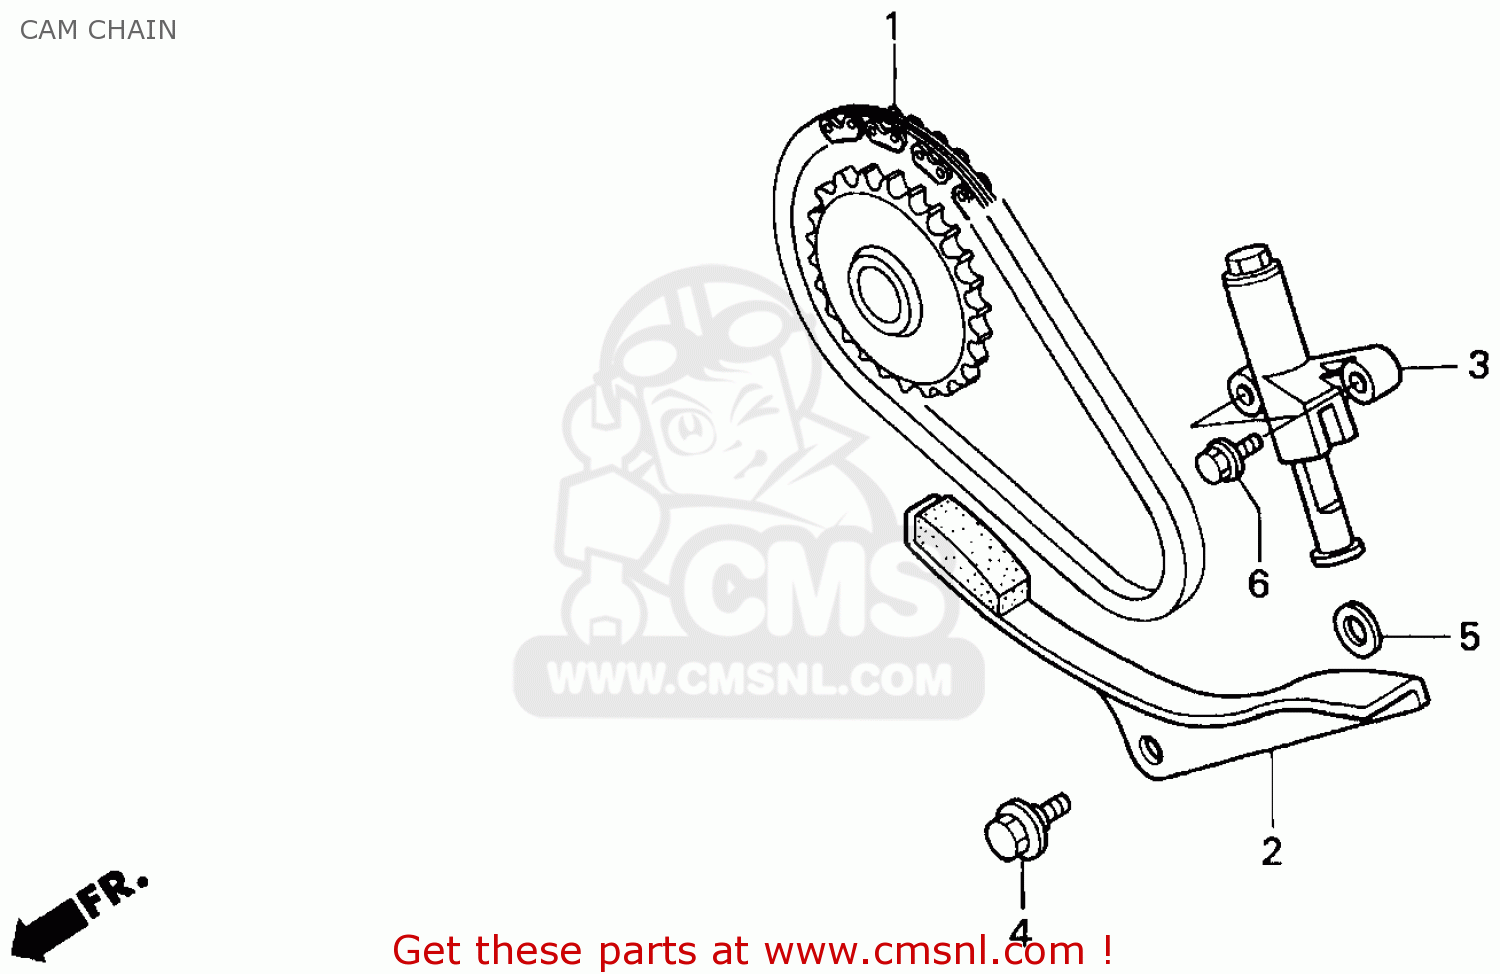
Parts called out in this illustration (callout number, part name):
1	CHAIN,CAM
2	ARM COMP,CAM CHAI
3	ADJUSTER,TENSIONE
4	PIVOT,SHIFT DRUM
5	WASHER,DRUM
6	BOLT,FLANGE,6X22
